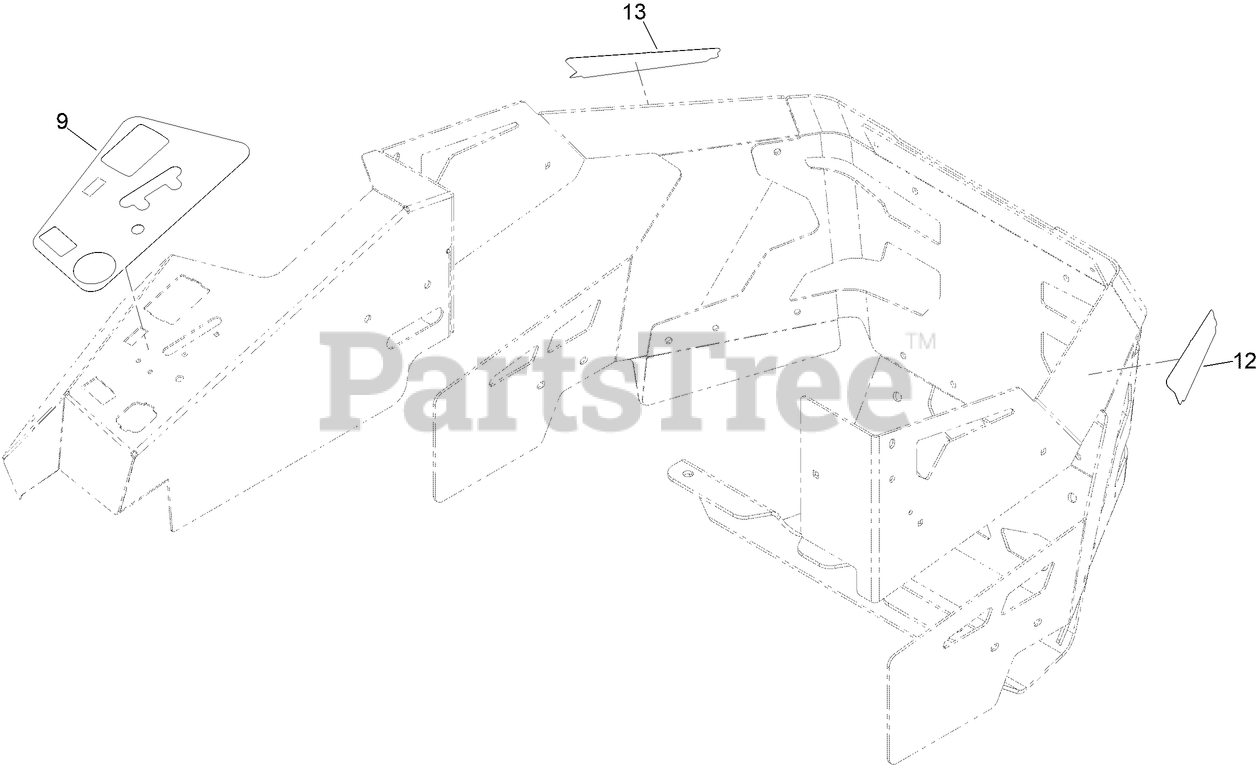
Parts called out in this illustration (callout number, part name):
9	DECAL-PANEL, CONTROL
12	DECAL-HDX PRO XL
13	DECAL-HDX PRO XL
